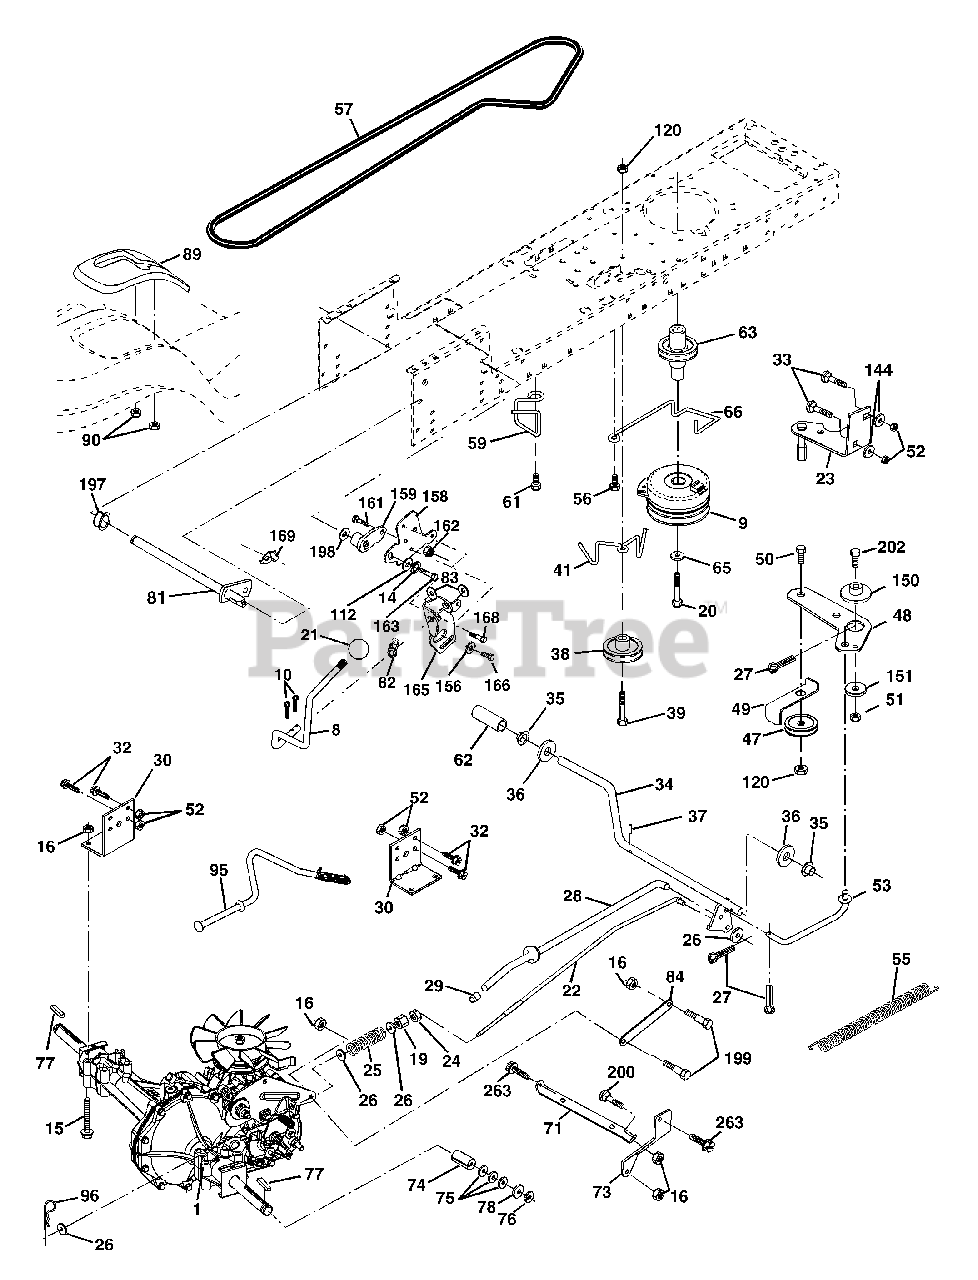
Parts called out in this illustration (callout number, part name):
8	Rod Shift Fender Adjust STLT
9	Clutch Elecric
10	Pin Cotter 1/8 x 1 CAD
14	Washer Lock Hvy Helical
15	Bolt Hex 5/16-18 unc Flghd
16	Nut Lock Hex W/Ins. 5/16-18 unc
19	Nut Lock Hex W/Ins 3/8-16 unc
20	Bolt, Hex 7/16-20 x 4-1/4
21	Knob Deluxe 1/2-13 unc BLK
22	Rod, Brake Hydro
23	Bracket Asm Anti-Rot EVX
24	Nut Hex Jam 3/8-16 unc
25	Spring, Brake Rod
26	Washer
27	Pin Cotter 1/8 x 3/4 CAD.
28	Rod, Parking Brake
29	Cap,Parking Brake
30	Bracket, Transaxle
32	Bolt Hex Hd 5/16-18 unc x 3/4
33	Bolt Carriage 5/16-18 unc x 3/4
34	Shaft, Foot Pedal
35	Bearing, Nylon
37	Pin, Roll
38	Pulley, Composite, Flat
39	Bolt Rdhd 3/8-16 unc x 2-3/4 Gr. 5
41	Keeper, Belt Idler
47	Pulley, Idler, V-Groove Plastic
48	Bellcrank Clutch Grnd Drv STL
49	Retainer, Belt Style Spring
50	Bolt Carr. Sh. 3/8-16 x 1-1/2 Gr. 5
52	Nut Crown Lock 5/16-18
53	Link, Clutch
55	Spring, Return, Clutch
56	Screw 3/8-16 x 1.0
57	V-Belt, Ground Drive
59	Keeper, Center Span
61	Screw 3/8-16 x .875
62	Cover, Pedal
63	Pulley, Egine
65	Washer Lock Hvy HLCL Spr 7/16
66	Keeper Belt Engine
71	Strap Torque Lh Hydro
73	Strap Torque Rh Hydro
74	Spacer, Axle
75	Washer 25/32 x 1-1/4 x 16 Ga.
77	Key, Square
78	Washer 25/32 x 1-5/8 x 16 Ga.
81	Shaft Asm Cross Tapered
82	Spring Torsion T/A
83	Washer 17/32 x 3/4 x 16 Ga.
84	Link Transaxle
89	Console, Shift
90	Nut Self Thd 1/4
95	Control Asm. Bypass Hydro
96	Retainer Spring 1" Zinc/Cad
112	Washer 9/32 x 3/4 x 10 Ga.
120	Nut Lock Flg 3/8-16
144	Washer 11/32 x 5/8 x 16 Ga.
150	Spacer Retainer
151	Washer 13/32 x 2 x 10 Ga.
156	Washer Srrted 5/16 ID x 1.125
158	Bracket Shift Mount
159	Hub Shift
161	Bolt Rdhd Sqnk 1/4-20 x 3/4 Gr. 5
162	Nut Crownlock 1/4-20 unc
163	Bolt Hex Fin 1/4-20 unc x 1 Gr. 5
165	Bracket Pivot Lever
166	Screw 5/16-18 x 5/8
168	Bolt Shoulder 5/16-18 x .561
169	Plate Fastening STLT/CRD
197	Nyliner Snap 5/8" ID
198	Washer Nyl 7/8 ID x .105 Hyd
199	Bolt Shoulder 5/16-18 unc
200	Bolt Rdhd Sqnk 5/16-18 unc x 1
202	Bolt 3/8-16 unc x 1-3/4 Gr. 5
